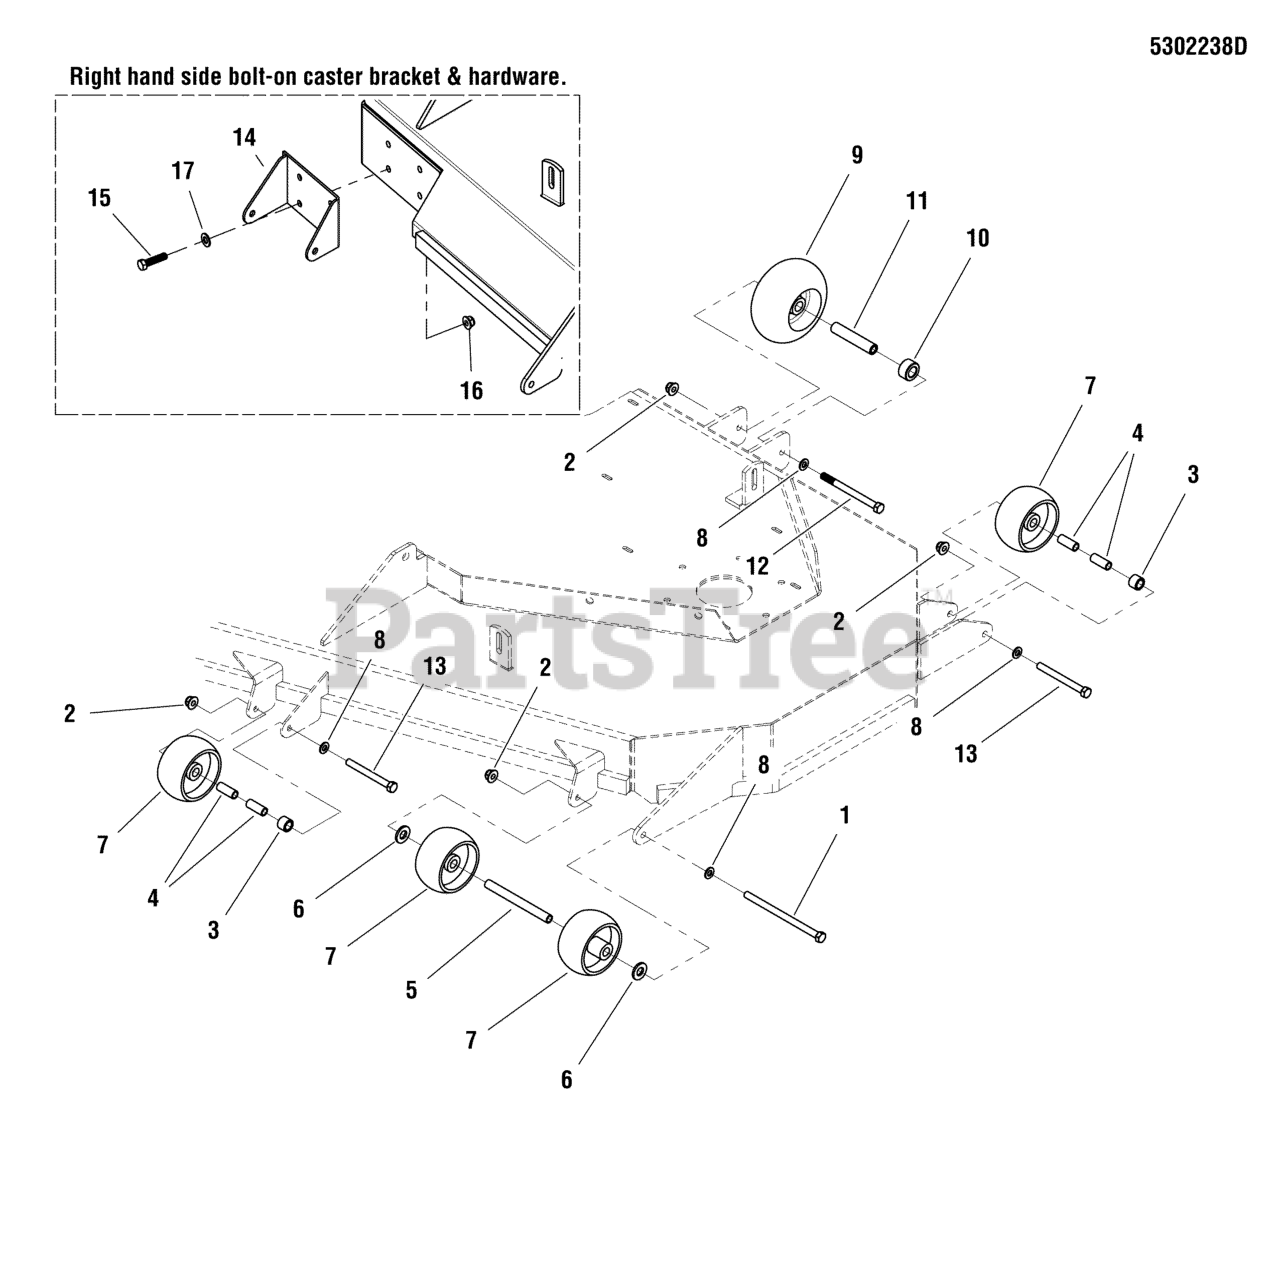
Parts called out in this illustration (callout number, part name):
1	BOLT, 3/8-16 X 6" GD5 CZ
2	NUT, 3/8-16 HEX NYLOCK FLANGE
3	SPACER, .51 X .75 X .56
4	SPACER, .38 X .50 X 1.25, CZ
5	SPACER, .38 X .50 X 5.06
6	WASHER, 1/2 GD9 YZ
7	WHEEL- 2.00 WIDE 3.88 DIA 0.531ID POLY
8	WASHER, 5/16" SAE
9	GAUGE WHEEL-2.70
10	SPACER, .64 X 1.13 X .63
11	SPACER, .38 X .63 X 3.25, YZ
12	BOLT, 3/8-16 X 4-1/2" GD5 CZ
13	BOLT, 3/8-16 X 3-1/2" GD5 CZ
14	PLATE, BRACKET, ANTI SCALP - RED
15	BOLT, 3/8-16 X 1" GD5 CZ
16	NUT, 3/8-16 HEX NYLOCK FLANGE
17	WASHER, 3/8 SAE
